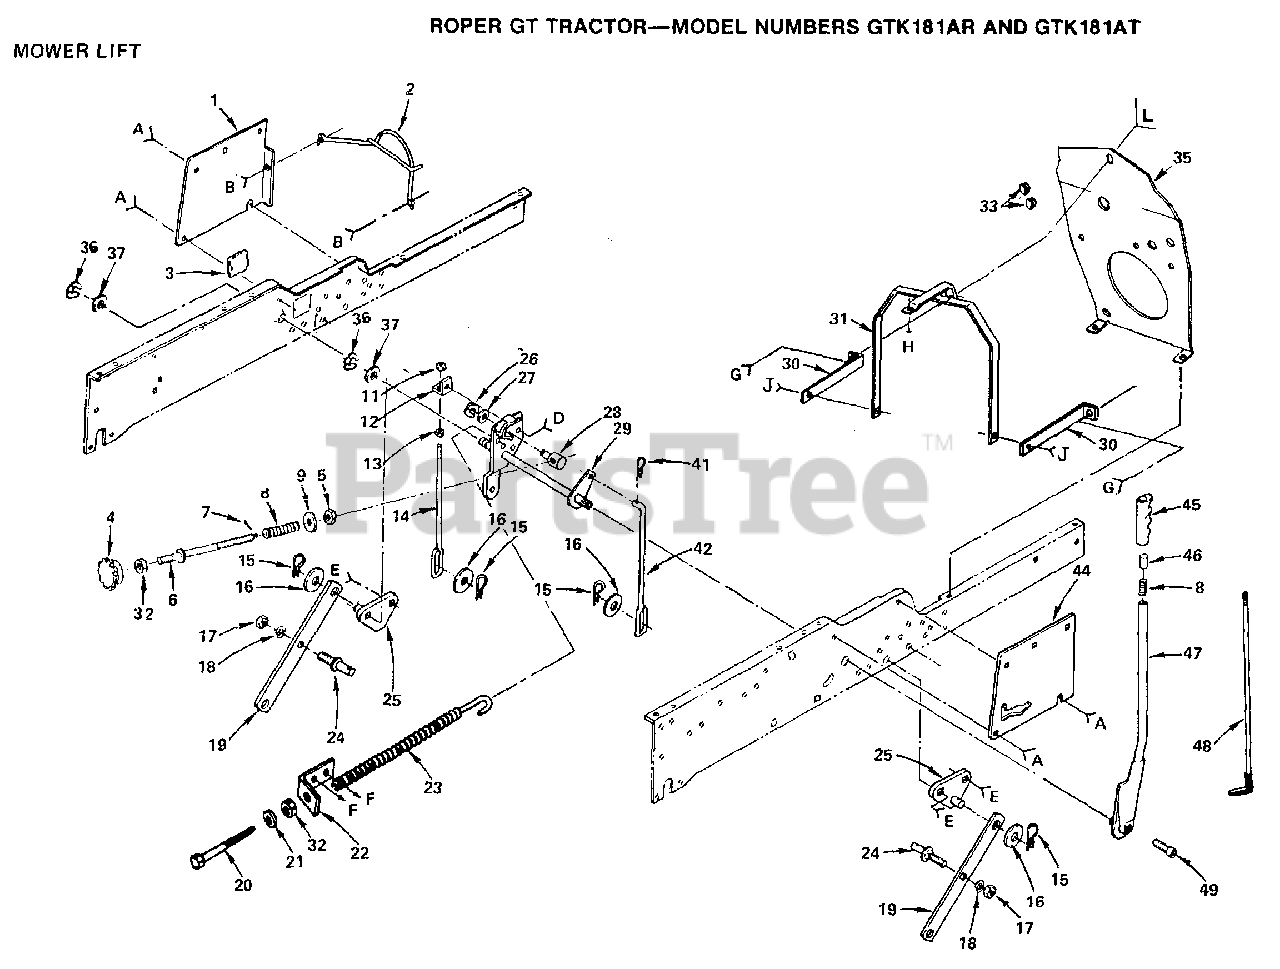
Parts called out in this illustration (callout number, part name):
5	NUT T
6	ROD ADJ. T
8	SPRING T
9	WASHER
11	NUT
12	BRACKET T
13	NUT.HEX.3/8-16UNC
14	LINK-LIFT MOW T
15	SPRING H
17	NUT
18	LOCKWASHER
19	SUSPENSION ARM GT
20	BOLT-ADJ SPRING T
21	WASHER
24	PIVOT STUD GT
25	SUSP BRACKET T
26	KLIP RING
27	WASHER
28	TRUNION LT
30	BRACKET T
32	NUT
36	E-RING
37	WASHER
42	LIFT LINK RH T
45	GRIP
48	LEVER ROD LT
49	"BOLT,HEX"
